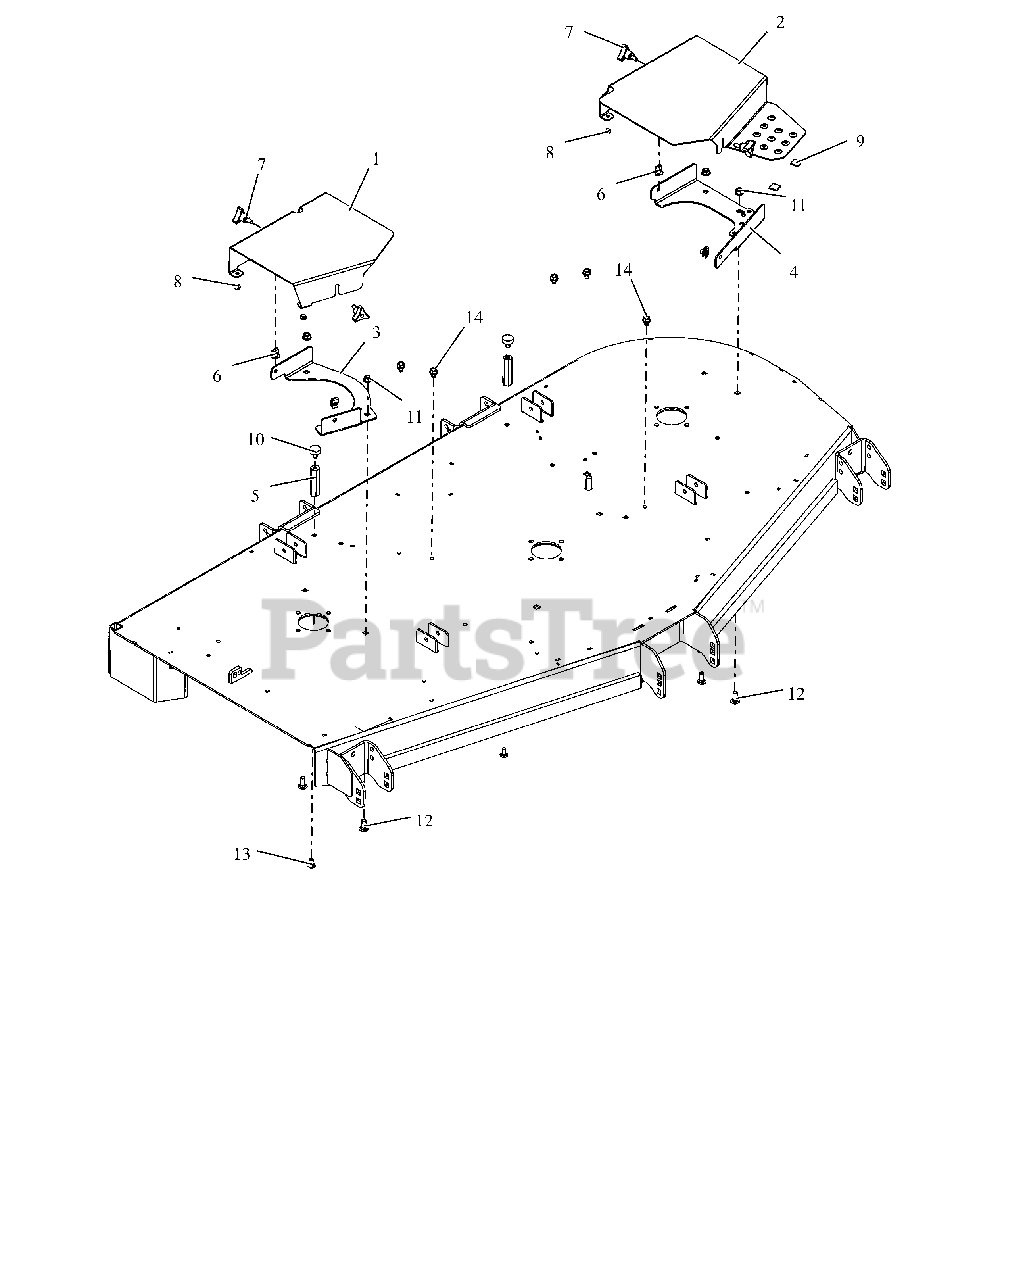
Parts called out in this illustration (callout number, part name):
1	GUARD, RH DECK - RED
2	GUARD, LH BELT - RED
3	BRKT, RH BELT GUARD MTG - RED
4	BRKT, LH BELT GUARD MTG - RED
5	NUT, COUPLING .31-18 X 3.00
6	NUT-CLIP RETAINER 5/16-18X.56
7	KNOB,WING STUD 5/16-18 X .75
8	BUMPER GROMMET
10	BUMPER, RUBBER
11	NUT,NYL-FLG .38-16 GF ZCC
12	BLT, RHSN .38-16X1.00 G5 ZCC
13	BTL,RHSN .313-18 X 0.75 G5 ZCC LT
14	SCR,TAP .375-16X.50 HWH TR ZCC
